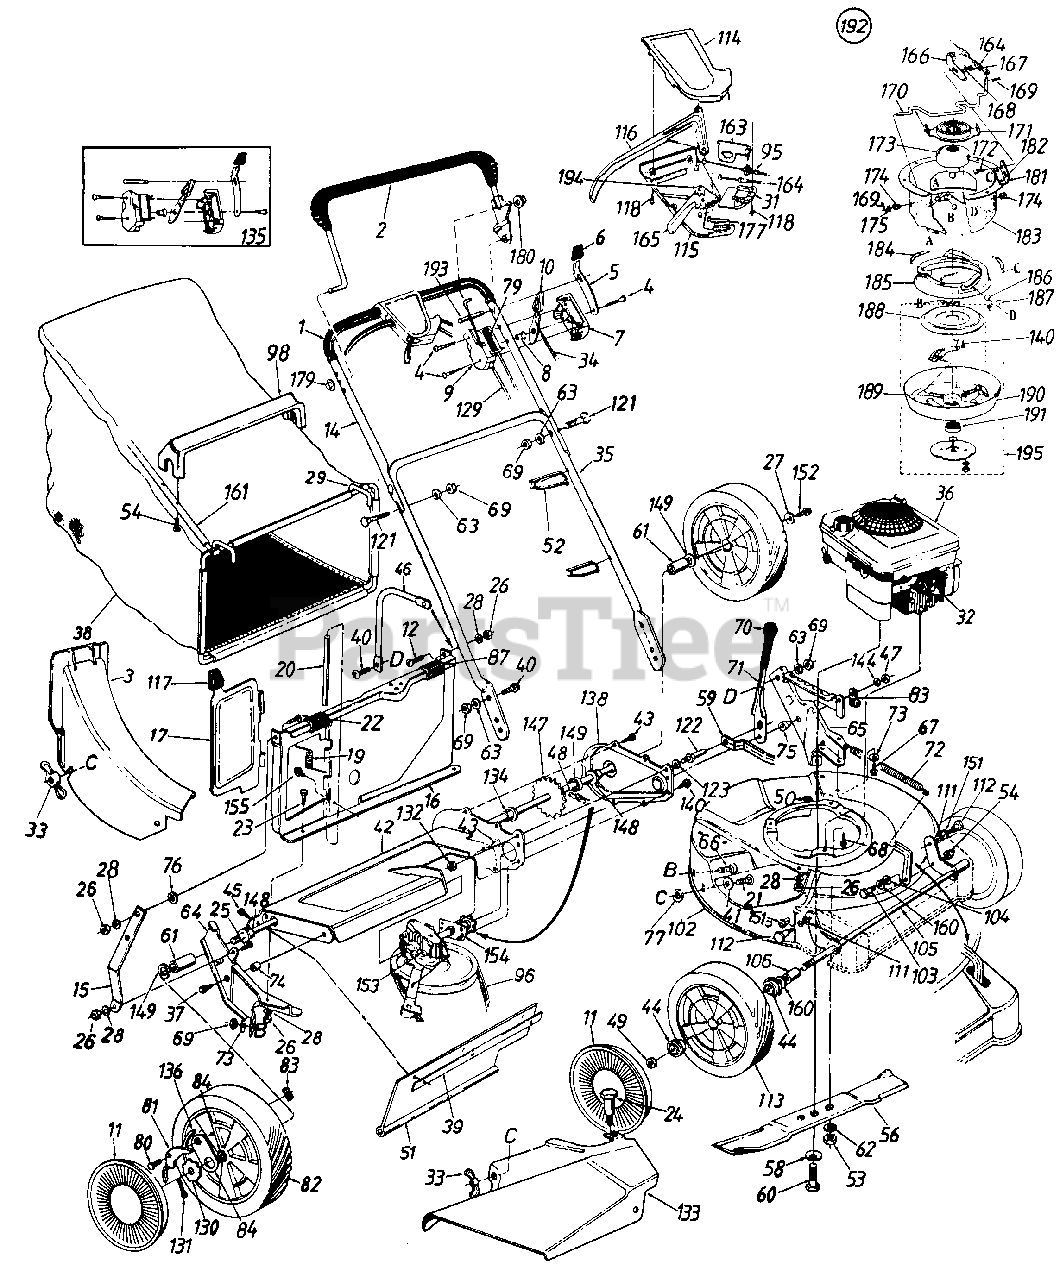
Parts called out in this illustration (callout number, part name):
1	GRIP-FOAM
3	CHUTE ASSY BLACK
4	SCREW-TRUSS MACH
5	SPRING-LOCKOUT
6	KNOB
7	PANEL HALF-CONTROL
8	PIN-CONTROL DISC
9	PANEL HALF-CLUTCH
10	LEVER-THROTTLE CONT-REV
11	HUB CAP
12	SCREW-TRUSS MACH
14	HANDLE-UPPER
19	SPRING-TORSION
21	BOLT-CARRIAGE 1/4-20 X .62
22	SCREW-TRUSS MACH
23	SCREW-HEX 1/4-20 X .50
24	SCREW-SHLD
25	SCREW-HEX 1/4-20 C .62
26	NUT-HEX 1/4-20
27	WASHER-SPRING BELL
28	LOCK WASHER 1/4 DIA
31	COVER-SP CONTROL
32	INSULATOR-SPARK PLUG
33	NUT-WING
34	WIRE-THROTTLE
35	HANDLE-LOWER PAINTED
38	BAG-GRASS-BLACK
39	STRIP-RETAINING
40	SCREW-TRUSS MACH 5/16-18 X .75
41	WASHER-FL-.344 ID X .62 OD X .033
44	BEARING-BALL
45	SCREW-HEX WASH HD
46	ARM-CATCHER SUPPORT
47	NUT-HEX LOCK 3/8-24
48	#48 CHAIN 1/2 PITCH
49	NUT-HEX INS L-1/2-20
52	TIE-CABLE
53	NUT-HEX 3/8-24
54	SCREW-HEX AB-TAP
56	BLADE-21IN
58	WASHER-BELL
59	ARM-HGT ADJ CONNECT
60	SCREW-HEX 7/16 N.F. X 2 GR.5
61	SPACER-.513 ID X .703 OD X .69
62	WASHER-LOCK-3/8
63	WASHER-LOCK-5/16
64	BRACKET ASSY-HDLE-RH
65	BRACKET ASSY-HDLE-LH
66	BOLT-CARRIAGE 5/16-18 X .62
67	SCREW-HEX WASH HD 5/16-18X1/2
69	NUT-HEX 5/16-18
71	LEVER-HGT ADJ
72	SPRING-EXTENSION
73	WASHER-BELL .337 X .867 X .057
74	SPACER
75	SPACER-SHLD .500 X .100
76	WASHER-FL-.285 ID X 1.25 OD X .060
77	RETAINER-BOLT 1/4X.50 OD
80	SCREW-SHLD .342 DIA X .268
81	PAWL
82	WHEEL ASSY W/TIRE
87	CLIP-PANEL BAG
95	CABLE-CLUTCH
96	BELT-V 3/8 X 31.0
98	HANDLE-BAG-BLACK
102	DECK ASSEMBLY-21IN
103	SCREW-SHLD .500 DIA X .295
104	WASHER-BELL .505 ID X 1.00 OD
105	AXLE ASSY
111	WASHER-INTERN L 3/8 X.56 OD X .018
112	SCREW-SHLD
113	WHEEL ASSY W/TIRE E
114	COVER-SP CONTROL-UPR
115	COVER-SP CONTROL-LWR
116	LEVER-CONTROL
117	KNOB
118	SCREW-FL C-SUNK AB
121	BOLT-CARRIAGE-CURV 5/16-18 X 1.38
122	PIN-SHLD 3/8-24X1.43 LG
123	WASHER-LOCK-3/8
129	CABLE-CLUTCH 49 IN
130	RATCHET
131	PIN-COTTER-1/8 DIA X 1.00
132	NUT-HEX JAM 3/8X24
133	DEFLECTOR-SIDE CHUTE
134	BEARING-HEX FLANGE
135	KIT-THROTTLE CONTROL
136	SPRING-NYLON
144	WASHER-FL-.385 ID X .87 OD X .06
147	SHAFT ASSY-REAR
148	BEARING-HEX FLANGE .506 ID
149	WASHER-FL-.531 X .930 OD X .050
151	BEARING-NYLINER
152	SCREW-1/4-20 X .62
153	TRANSMISSION-COMP
155	SCREW-HEX B-TAP #10 X .38
160	WASHER-FL-.510 ID X .75 OD X .033
163	BRACKET-CABLE
164	CABLE-SPEED CONTROL
165	LEVER-6 SPEED SHIFT
168	WASHER-SPRING BELL
169	PIN-COTTER-3/32 DIA X .75
170	ROD-SHIFT-LH
171	PULLEY ASSY-MOVEABLE
172	BOLT-CARRIAGE 1/4-20 X .50
173	ADAPTER-FIXED PULLEY
174	BUSHING-FLANGED
175	WASHER-FL
177	SPRING-SHIFT LEVER
179	NUT-SPEED
181	BRACKET-MTG
182	RIVET
183	HOUSING-CLUTCH
184	SPRING-EXTENSION
185	CONE-BRAKE CUP
186	BALL-STEEL
187	BALL-BLOCK
188	CONE-CLUTCH
190	HOUSING-CLUTCH BLADE
191	BEARING-BALL
192	CLUTCH ASSY-BBC-COMP
193	PIN-LOCKING
194	INSERT-3 TOOTH RACK
195	HOUSING ASSY-W/FPA
16862-0637	PANEL ASSEMBLY-CATCHER(POWDER BLACK) - POWDER BLACK (0637)
16862-0638	PANEL ASSEMBLY-CATCHER(MTD RED) - MTD/TROY-BILT RED (0638)
16862-0648	PANEL ASSEMBLY CATCHER(TECH GRAY) - TECH GRAY (0648)
16862-0662	PANEL ASSEMBLY-CATCHER(OYSTER GRAY) - OYSTER GRAY (0662)
16862-0665	PANEL ASSEMBLY-CATCHER(YARD-MAN GREEN) - YARDMAN GREEN (0665)
17053A-0483	COVER-CHAIN - CHARCOAL GRAY (0483)
17053A-0637	COVER-CHAIN (POWDER BLACK) - POWDER BLACK (0637)
17053A-0638	COVER-CHAIN - MTD/TROY-BILT RED (0638)
17053A-0650	COVER-CHAIN - RED METALLIC (0650)
17053A-0662	COVER-CHAIN - OYSTER GRAY (0662)
17053A-0665	COVER-CHAIN - YARDMAN GREEN (0665)
17053A-0674	COVER-CHAIN - YARDMAN YELLOW (0674)
17055B-0498	AXLE ASSEMBLY-CHAIN (CUB YELLOW) - OLD CUB YELLOW (0498)
17055B-0629	AXLE ASSEMBLY-CHAIN SILVER FLAK - SILVER FLAKE (0629)
17055B-0637	AXLE ASSY-CHAIN - POWDER BLACK (0637)
17055B-0638	AXLE ASSY-CHAIN - MTD/TROY-BILT RED (0638)
17055B-0648	AXLE ASSEMBLY-CHAIN (TECH GRAY) - TECH GRAY (0648)
17055B-0650	AXLE ASSEMBLY-CHAIN RED METALL - RED METALLIC (0650)
17055B-0662	AXLE ASSEMBLY-CHAIN (OYSTER GRAY) - OYSTER GRAY (0662)
17055B-0667	AXLE ASSEMBLY-CHAIN MIDNIGHT BL - MIDNIGHT BLUE (0667)
17055B-0691	AXLE ASSEMBLY-CHAIN (BLACK JACK) - BLACK JACK (0691)
